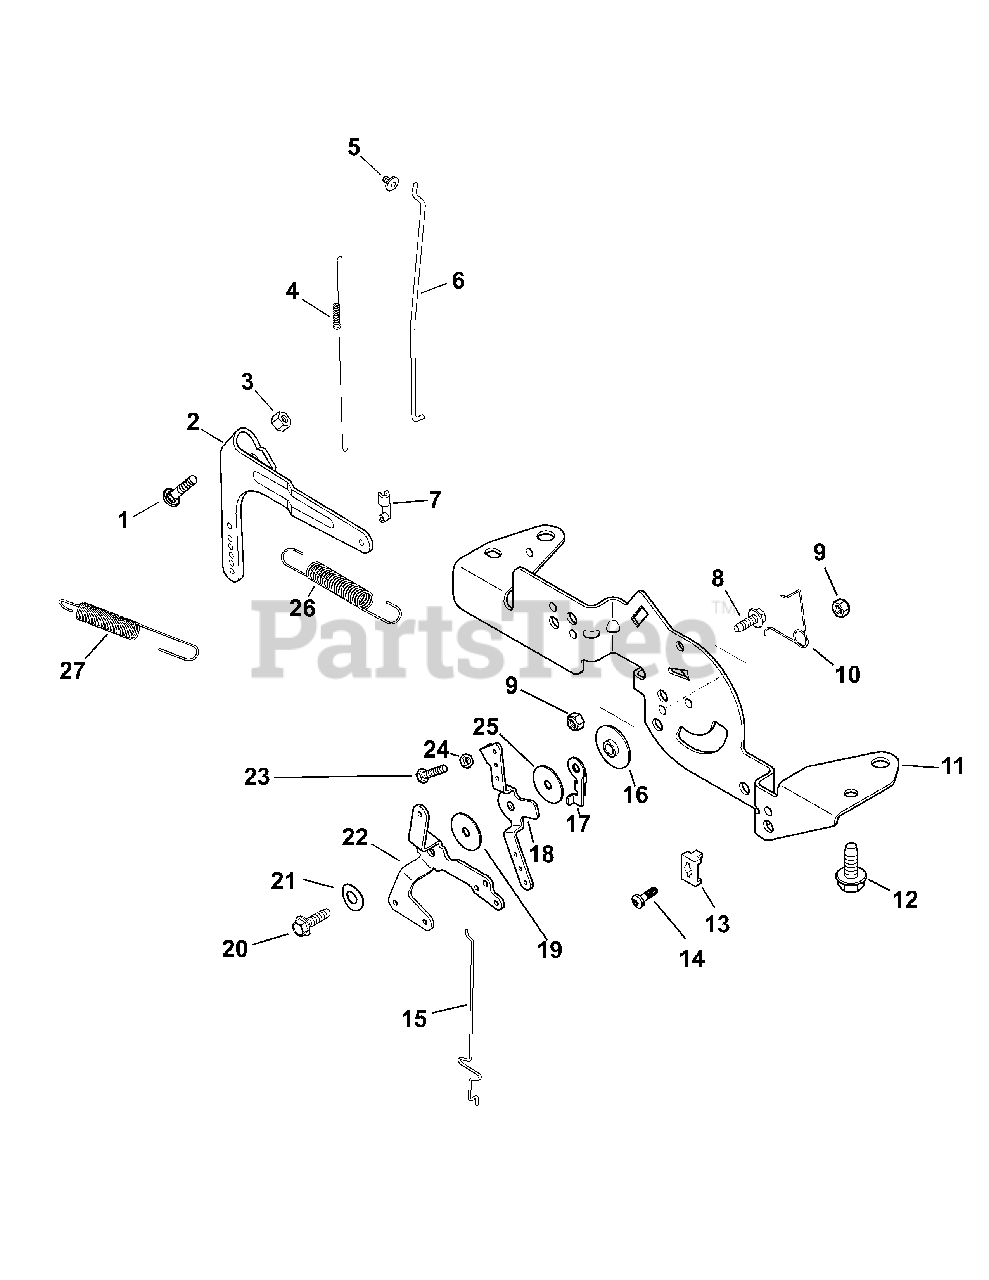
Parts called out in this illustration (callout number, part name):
1	Rd. Hd. Sq. Neck Bolt, M6 x 1.0 x 25
2	Governor Lever
3	Flg. Nut, M6 x 1.0
4	Linkage Spring
5	Linkage Retaining Bushing
6	Throttle Linkage
7	Throttle Linkage Bushing
8	Screw, M5 x .8 x 16
9	Lock Nut, M5 x .8
10	Choke Return Spring
11	Control Bracket
12	Flg. Thd. Frm. Screw, M6 x 1.0 x 16
13	Cable Clamp
14	Lbd. Thd. Frm. Screw, M5 x 0.8 x 16
15	Choke Linkage
16	Control Assembly Spacer
17	Throttle Actuator Lever
18	Throttle Control Lever
19	Flat Washer, 5.5MM
20	Screw, M5 x .8 x 20
21	Spring Washer, 1/4"
23	Screw, M4 x .7 x 25
25	Flat Washer, 5MM
26	Governor Spring
27	Governor Spring
